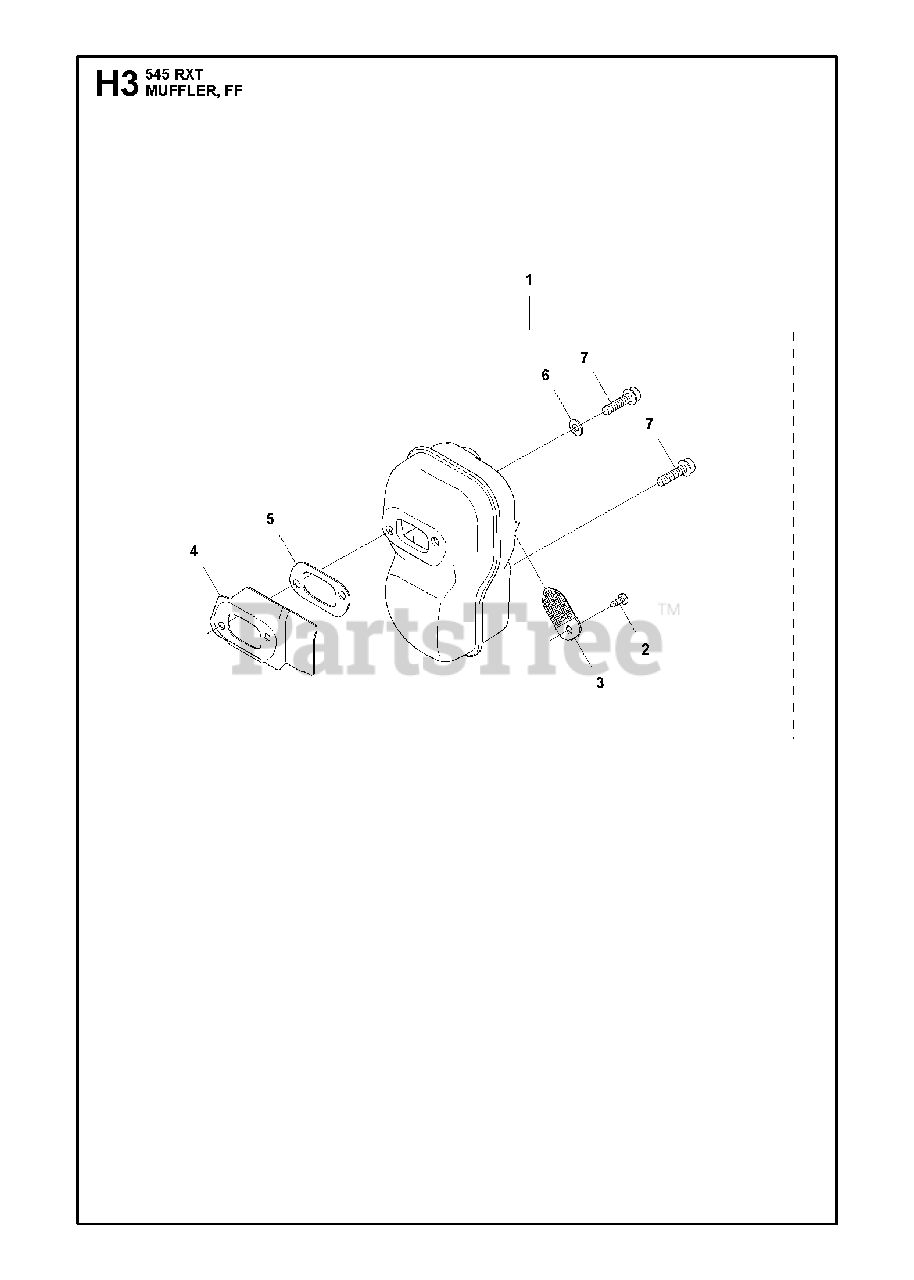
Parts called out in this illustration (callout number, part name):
1	MUFFLER KIT EXHAUST DUCT
2	SCREW
3	SPARK ARRESTOR SCREEN
4	HEAT DEFLECTOR
5	GASKET
6	DOUBLE WASHER
7	SCREW
